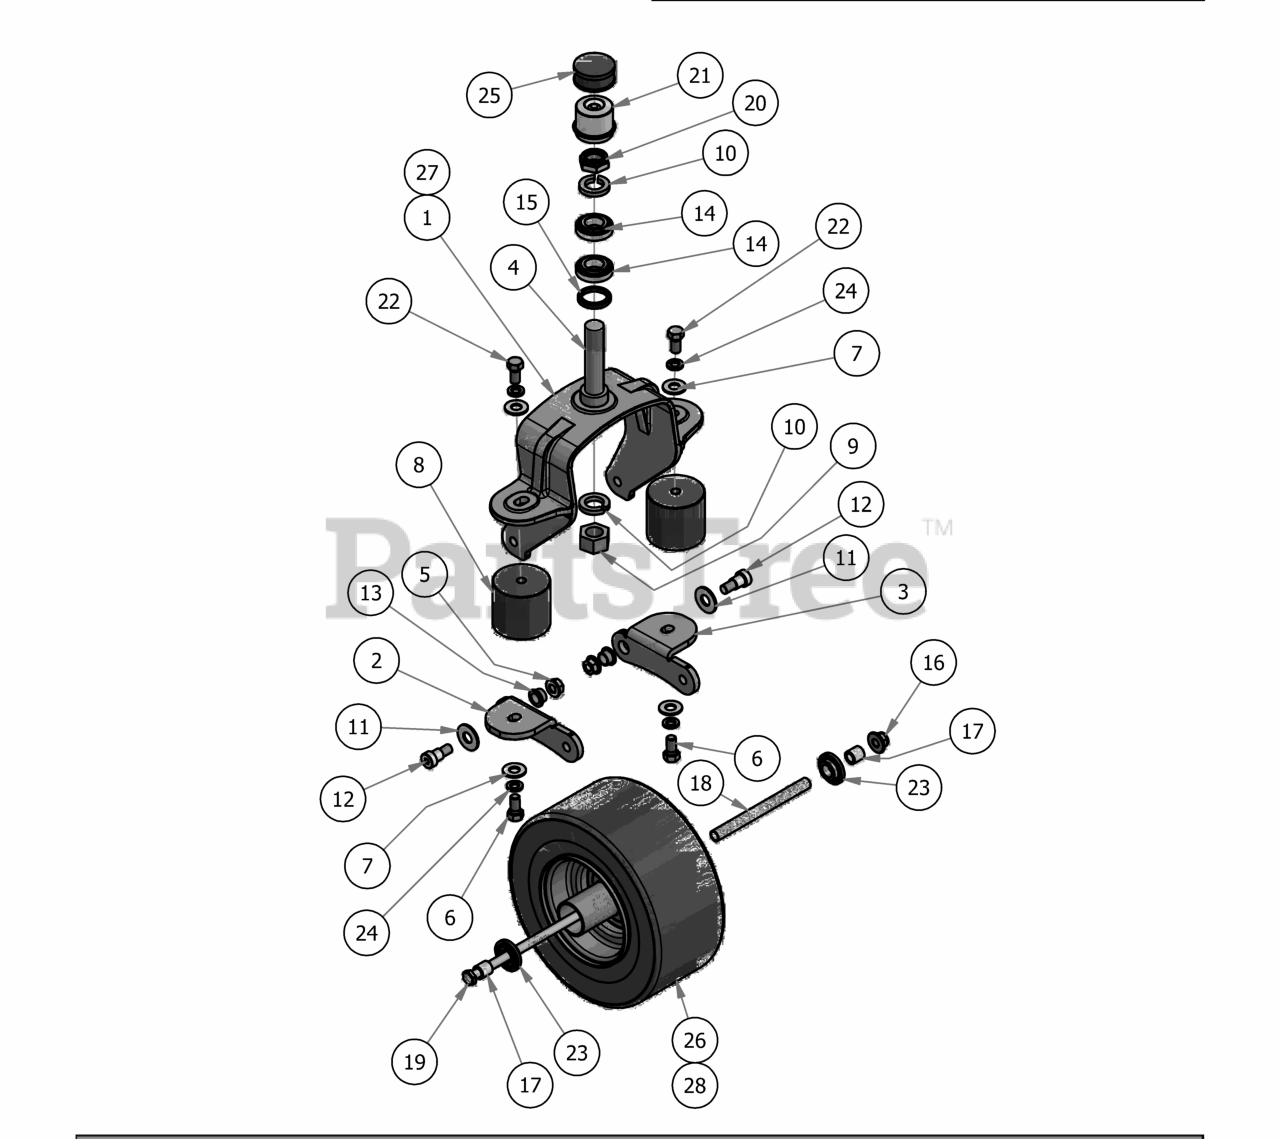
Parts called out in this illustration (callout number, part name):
1	Suspension Fork Top/Side Combo
2	Suspension Fork - Bottom Left
3	Suspension Fork - Bottom Right
4	Front Suspension Fork Spindle
5	1/2" Flange Nut
6	1/2" x 1" Hex Bolt
7	1/2" Washer (Grade 8)
8	Vibration Mount- Red Dot
9	1" Fine Thread Nut
10	1" Lock Washer
11	5/8'' Flat Washer
12	5/8'' x 5/8'' Shoulder Bolt
13	Bronze Bushing - SF - 2024-8
16	1/2-13 Nylon Flange Nut
17	Spacer 3/4 OD x 1/2 ID x 3\4 Length
18	Front Wheel Spanner
19	1/2'' x 10'' Bolt
20	1" Fine Thread 1/2 Nylock Nut
21	Dust Cover
22	1/2" x 1-1/4" Gr5 Hex Bolt (Coarse)
23	1-3/4" Bearing-Large Bore Front Rim
24	1/2" Lock Washer
25	Spring Cap Cover
26	13 x 6.50 - Reliance No-Flat
27	Suspension Fork Assembly
28	13 x 6.50 - No-Flat Large Bore Orange front Assembly
